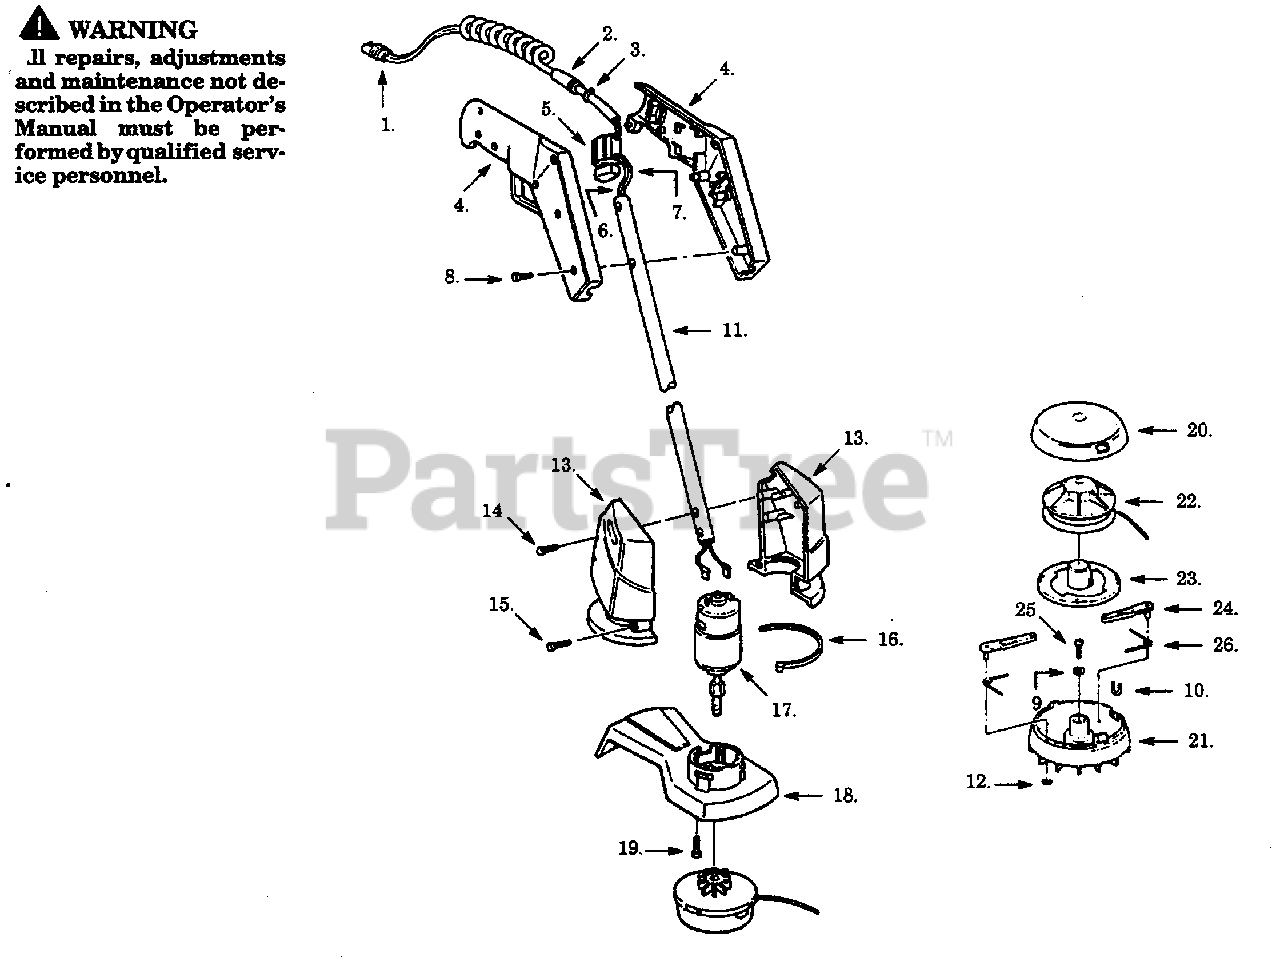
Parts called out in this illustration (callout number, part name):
2	Rubber Strain Relief
3	Strain Relief
4	Handle Set
5	Trigger Switch
6	Lead Wire (Black)
7	Lead Wire (Red)
10	Line Shield
13	Housing Set
16	Tie Wrap
17	Motor/Adapter Assy
18	Guard/Blade Assy.
21	Housing Assy.
22	Spool & Line
